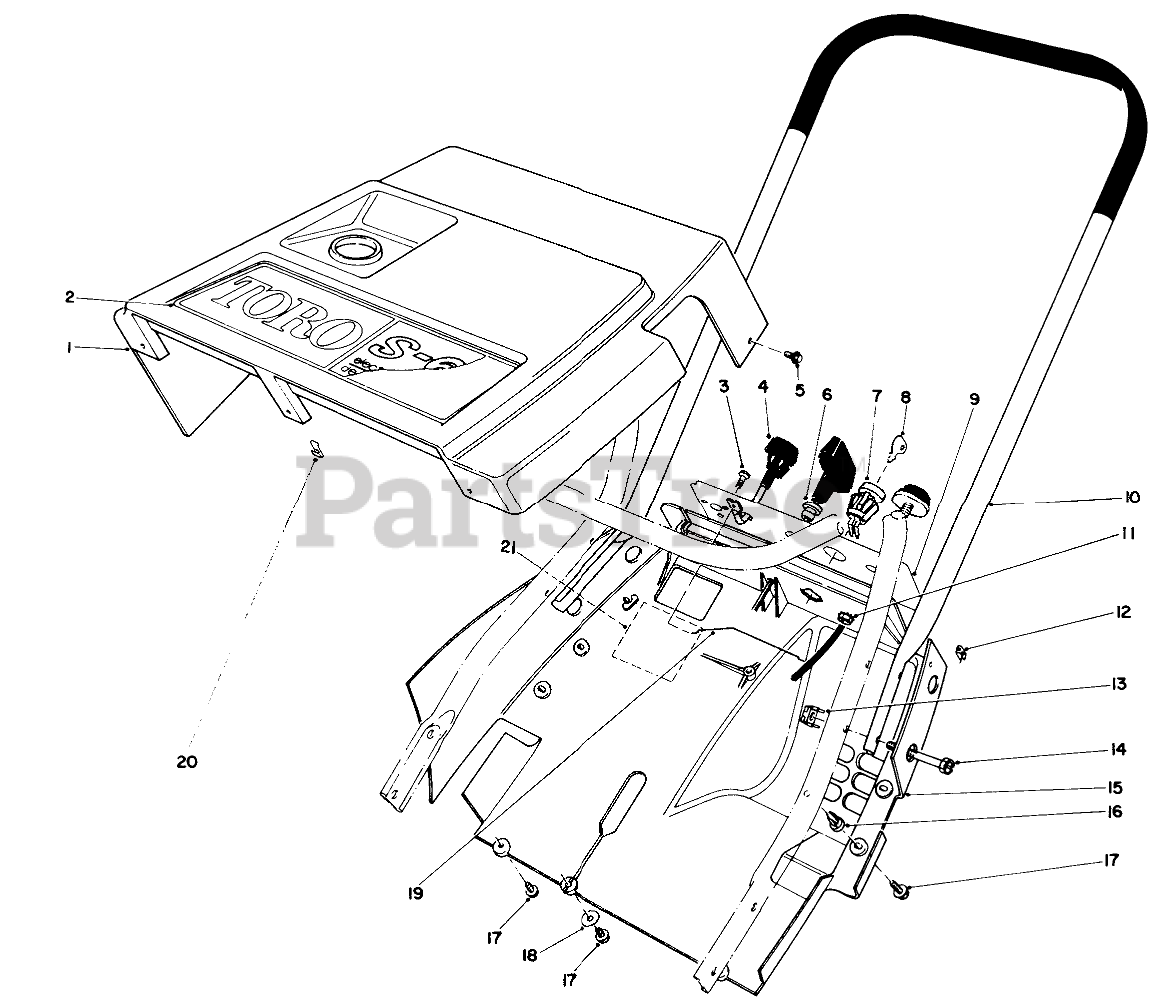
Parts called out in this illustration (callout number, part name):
1	Shroud-Upper
2	TORO DECAL
3	SCREW-PLASTITE
4	CHOKE CONTROL ASM
5	SCREW-HWHTF
6	GUIDE-ROPE, STARTER
7	SWITCH
8	KEY-IGNITION
9	Decal-Control Panel
10	Handle-Upper
11	NUT-KEPS
13	TINNERMAN NUT
14	SCREW-HEX HD SLOT
15	LOWER SHROUD
16	Nut-Push
17	SCREW-HWHTF
18	WASHER-FLAT
19	CONTROL WIRE
20	NUT "U"
21	DECAL - CSA
